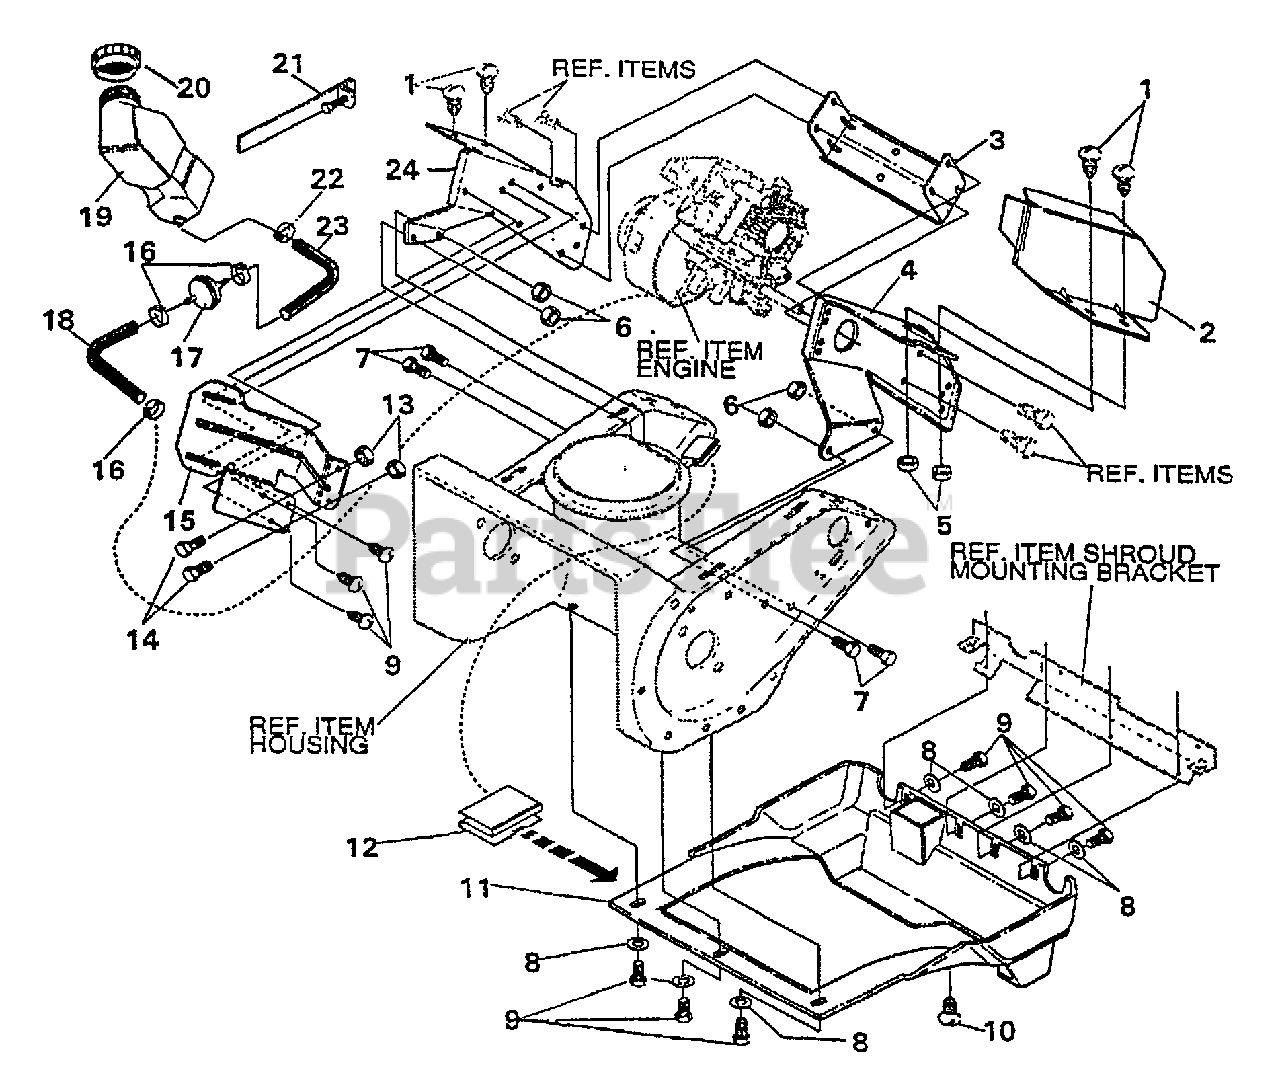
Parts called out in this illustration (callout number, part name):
1	SCREW - 1/4-20 X 5/8"
2	SHIELD, HEAT
3	SUPPORT, FRAME
4	PLATE, REAR MOUNT -- LEFT
5	LOCKNUT - 1/4-20
6	NUT - 5/16-18
7	SCREW - 5/16-18 X 1/2"
8	WASHER
9	SCREW - 10-24 X .63"
10	SCREW - 10-16 X .50"
11	SHROUD, BOTTOM
12	CLIP
13	LOCKNUT - 10-24
14	SCREW - 10 X 24 X .50"
15	BRACKET, FUEL TANK
16	CLAMP, HOSE
17	FILTER, FUEL
18	TUBING, GAS LINE 30"
19	TANK, FUEL - 6.2 QUART
20	CAP, FUEL
21	CLAMP, WORM DRIVE
22	CLAMP, HOSE
23	TUBING, GAS LINE 8"
24	PLATE, REAR MOUNT -- RIGHT
